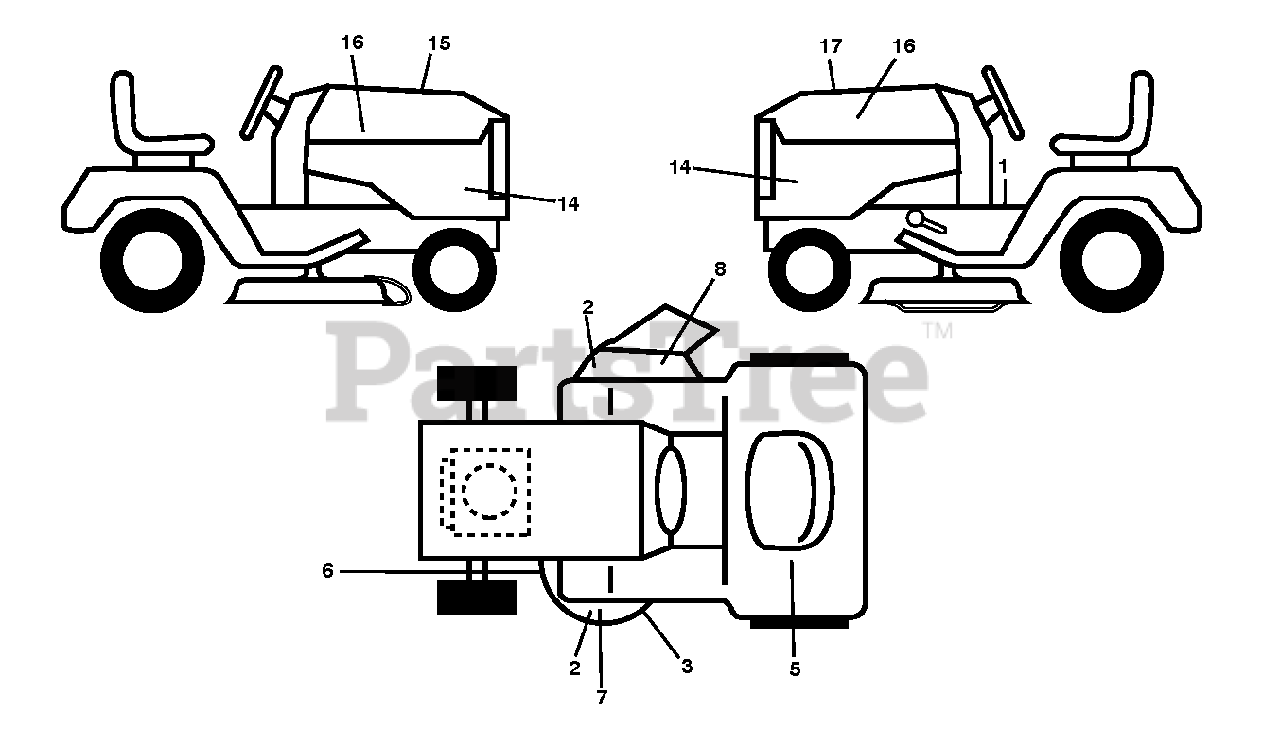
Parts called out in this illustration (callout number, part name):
1	DECAL.FENDER.WARNING.ENGLISH
2	DECAL.DECK.CLEARCUT.NOSTEP
3	DECAL.MOWER.SCH.48/54.PREM
5	DECAL.RESERVEFUELSELCTR.ENG
6	Deck Decal, WA
7	Deck Decal, 48"
8	DECAL.TRACT/ZTR.DECKWARN.HUSQ
14	DECAL.SDPNL.HUSQGT.TS348.RH/LH
15	DECAL.WARNING.CUST.RESP.E85.
16	DECAL.BADGE.170MM.TEXTLOGO.
17	DECAL RPL K66.48F.KOH KT7.TGB
